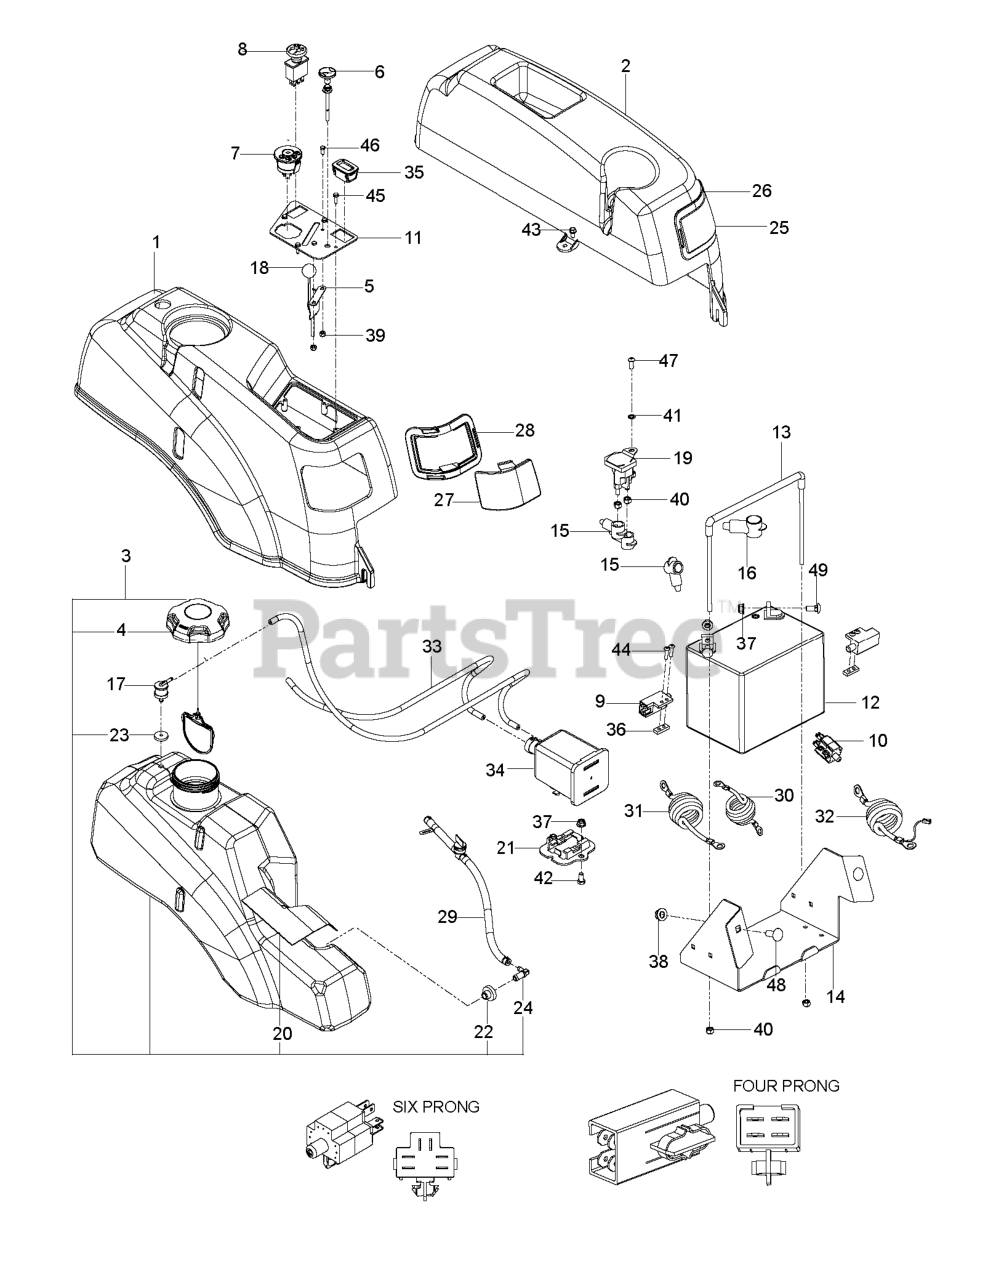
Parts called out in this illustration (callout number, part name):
1	FENDER RT, GRAY
2	FENDER, LT
3	TANK.FUEL.ASSEMBLY.LARGE
4	CAP, FUEL
5	THROTTLE CABLE
6	CHOKE CABLE
7	RP IGNITION SWITCH
8	RP SWITCH.PTO.8.TERMINAL.RED
9	SWITCH, BRAKE 3P
10	SWITCH INTERLOCKT
11	CONSOLE.PLATE.BLACK
12	BATTERY, 12 V 330 AMP
13	BATTERY TIE DOWN ASSEMBLY
14	BOX, BATTERY, BLACK
15	TERMINAL COVER-SM
17	VALVE.FUEL.CHECK
18	KNOB.ROUND.BALL.BLACK
19	SOLENOID.W/BRASS.PLUNGER
20	SHIELD, HEAT
21	BRACKET, CANISTER
22	RUBBER GROMMET
23	GROMMET, CHECK VALVE
24	STEM, FUEL TANK
25	LENS, COLORED LEFT
26	LEFT HEADLIGHT RIM GREY
27	LENS, COLORED RIGHT
28	RT HEADLIGHT RIM GREY
29	FUEL LINE ASSY
30	CABLE POSITIVE, LONG
31	BATTERY CABLE, NEGATIVE
32	CABLE POSITIVE LONG W/LEAD
33	FUEL LINE 33"
34	CANNISTER, CARBON
35	RP.GUAGE.SRVCMNDR.HRMTR.
36	TAPPED PLATE
37	5/16-18 NYLOC FLANGE NUT
38	NUT 3/8-16 HEX FLG NYLOC ZD
39	NUT 10-24 NYLOC
40	NUT.1/4-20.HEX.NYLOC.ZD
41	WASHER 1/4 INT TOOTH
42	HCS 5/16-18 X 5/8 GR 5 ZD
43	BOLT 1/4-20 X 1/2 HWST
44	SCR #10-24 X .75 SKT HD BLK
45	SCR #10-12X3/4 HEX WAS HD ZD
46	HCS #10-24 X 1/2
47	SCR 1/4-20 X 5/8 BTN SKT HD ZD
48	RHSNB 3/8C X 1
49	BOLT 5/16C X 3/4" CARRIAGE
